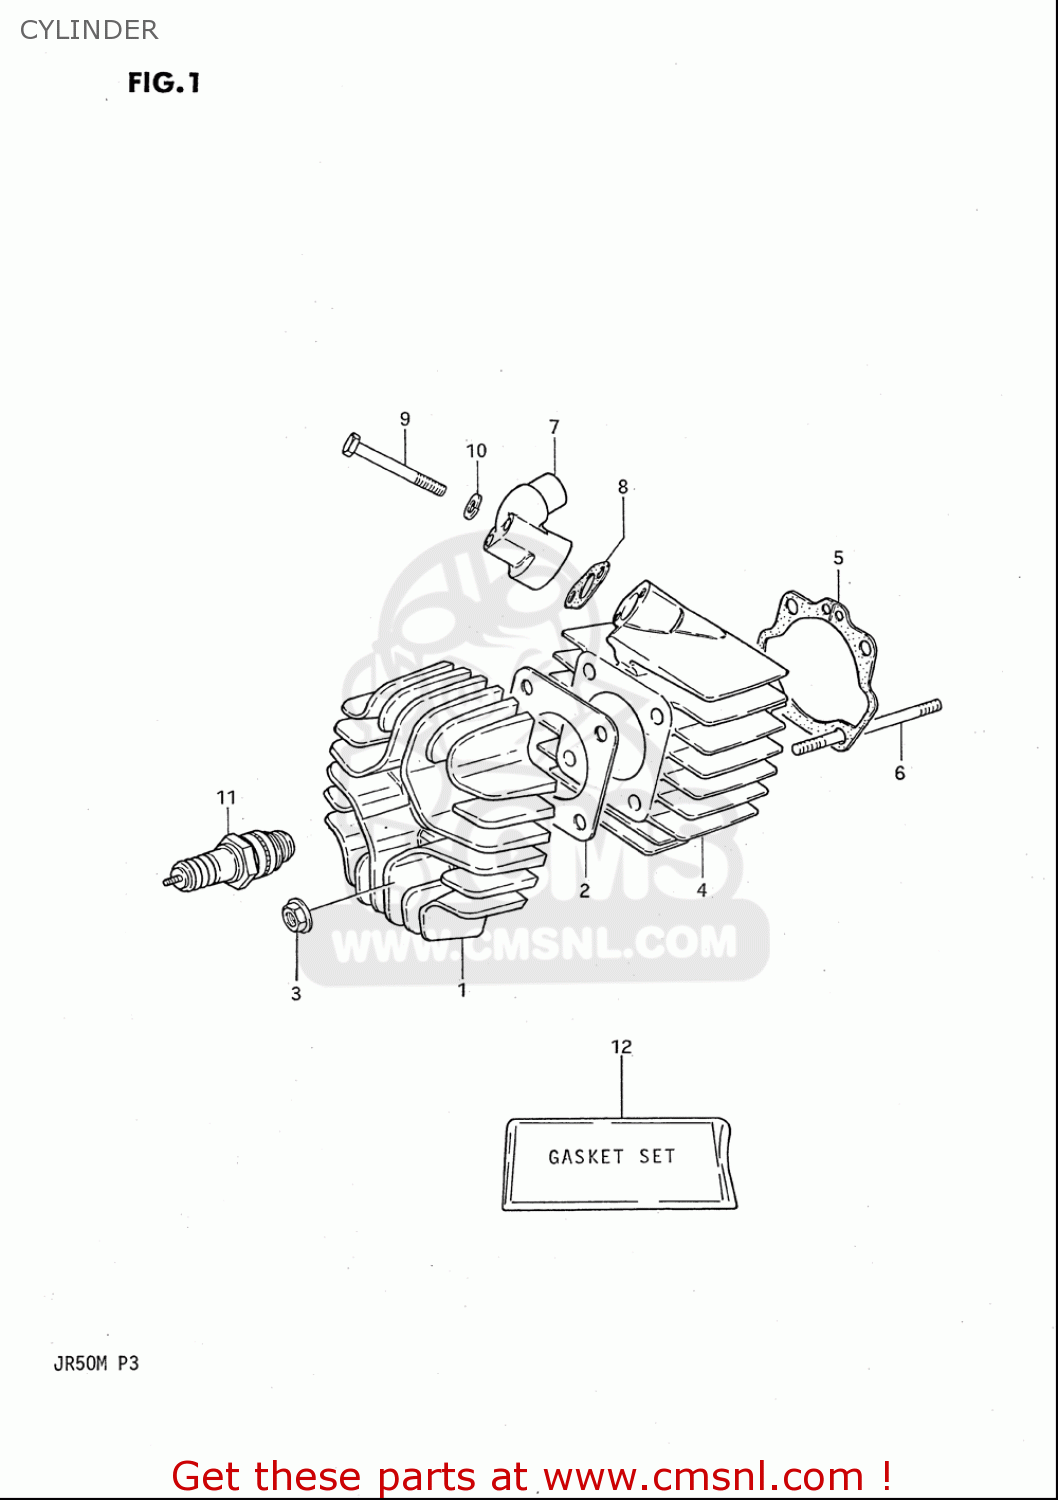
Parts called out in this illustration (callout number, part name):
1	HEAD,CYLINDER
2	GASKET,CYLINDER HEAD (NAS)
3	NUT
4	CYLINDER
5	GASKET,CYLINDER (NAS)
6	BOLT,STUD
7	PIPE,INTAKE
8	GASKET,INTAKE PIPE (NAS)
9	BOLT 6X45
10	WASHER,LOCK
11	PLUG,SPARK(BP4H)
12	GASKET SET (NAS)
